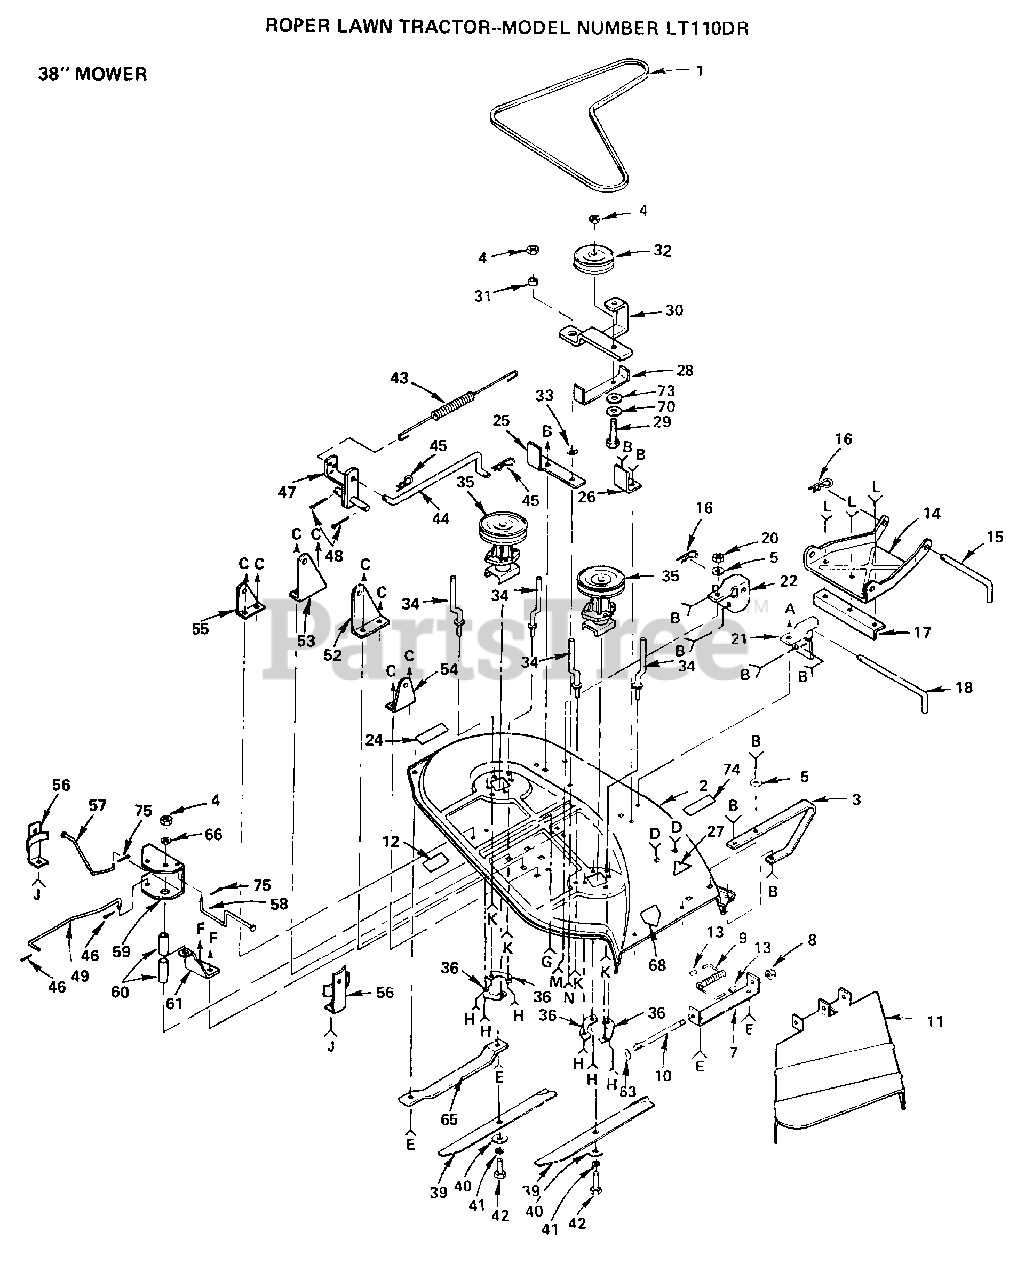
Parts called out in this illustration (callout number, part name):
1	BELT-V.79.1.MWR
5	WASHER M
10	ROD-HINGE T
11	DEFLECTOR-SHLD T
12	DECAL.LT
13	CAP-SLEEVE LT
14	LINK.PARALLEL
15	"ROD, FRT. PARAL T"
16	RETAINER.SPRING
17	LINK STOP
24	DECAL INSTRUCTION CAUTION
27	DECAL - SAFETY STANDARD
31	SPACER RETAINER
32	IDLER-FLAT T
33	"WASHER, WEAR LT"
34	BELT KEEPER LT
36	SUPPORT PLATE LT
40	WASHER
41	LOCKWASHER
42	BOLT.3/8-24X1-1/2
45	SPRING.RETAINER
47	ROCK SHAFT LT
49	ROD BRAKE LT
54	"BRKT,SUSP RH T"
56	BRAKE LT
57	"ROD, BRAKE LH LT"
58	ROD BRAKE LT
59	"BRK,BRAKE,PVT LT"
60	SPACER BRAKE LTV
61	BRACKET SUPT LTV
63	WASHER
65	RUNNER-LH M
66	WASHER
70	WASHER
73	WASHER
74	DECAL.WARNING.T
